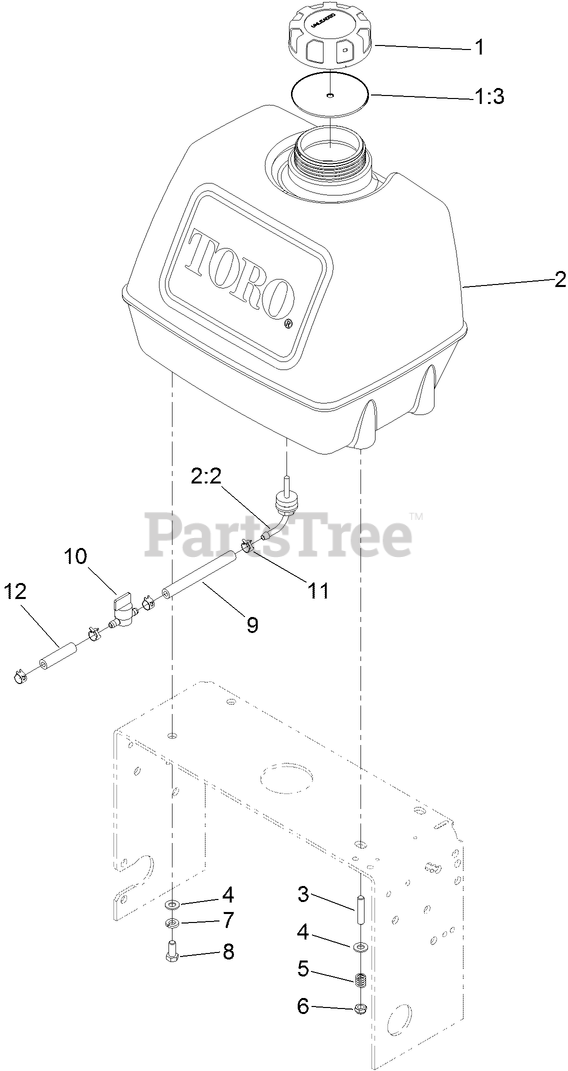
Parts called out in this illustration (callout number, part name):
1	GAS CAP ASM
1:3	GASKET-CAP, GAS
2	FUEL TANK ASM
2:2	FITTING-FUEL, BULKHEAD
4	WASHER-PLAIN
5	SPRING-TANK, FUEL
6	NUT-LOCK, NI
7	WASHER-LOCK
8	SCREW-HH
9	HOSE-FUEL
10	VALVE-FUEL
11	CLAMP-HOSE
12	HOSE-FUEL
